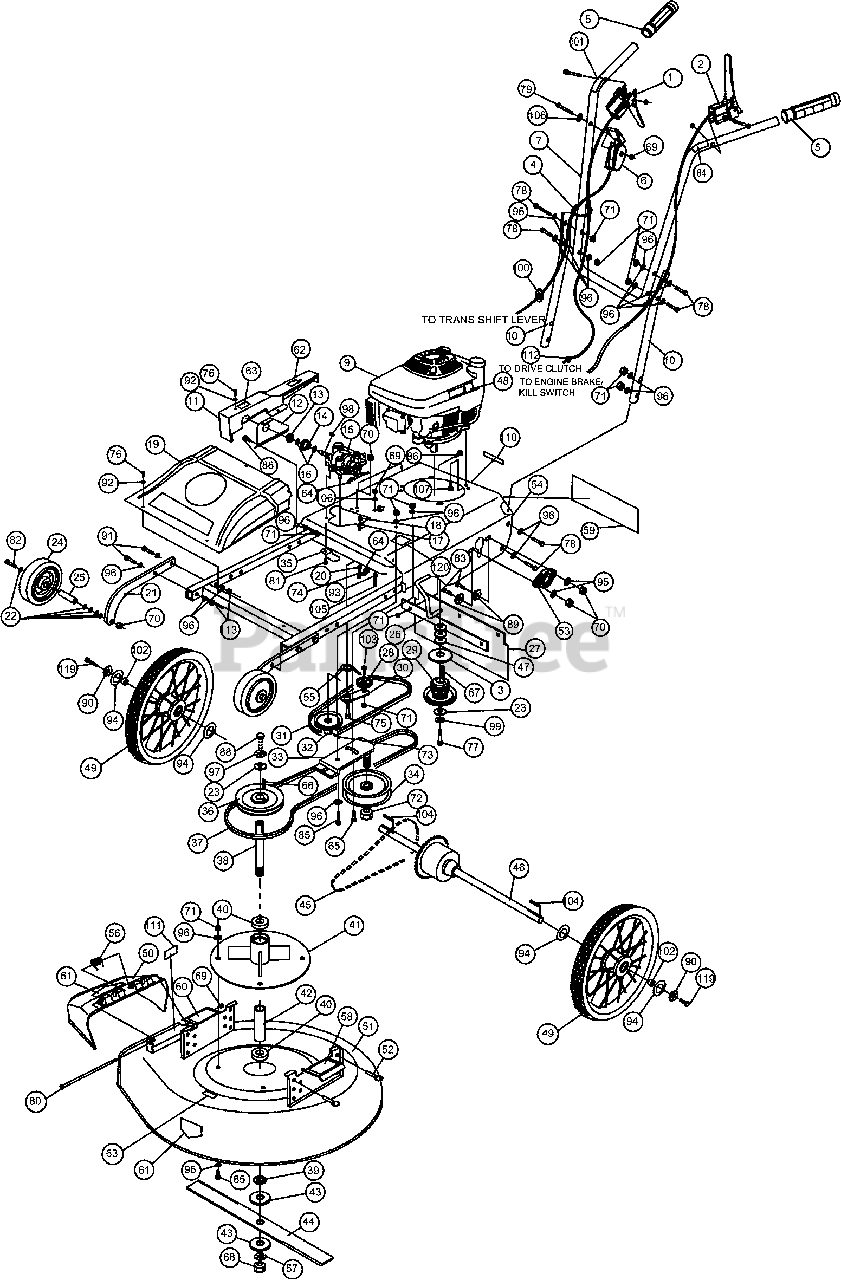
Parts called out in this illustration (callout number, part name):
1	LEVER DRIVE CLUTCH W/CABLE
2	LEVER ENGINE BRAKE W/CABLE
3	SPACER 1" ID X 2" OD
5	GRIP HANDLE 1” ID X 5” BLACK
6	CONTROL SHIFT 3 SPEED
7	HANDLE UPPER HW
9	ENGINE 6.5 HONDA OHV
10	HANDLE LOWER HW
11	CHAIN GUARD HW
12	PLATE BEARING RIGHT
13	BEARING 1/2 CLIP
14	8 TOOTH SPROCKET
15	TRANSMISSION 3 SP
16	C-CLIP 1/2
17	WASHER #10 SAE
18	LOCK NUT #10
19	BELT GUARD HW
20	NUT #10 HEX
21	FRONT WHEEL BRACKET
22	WASHER 1/2” ZP
23	WASHER 1/2" - .453 ID
24	WHEEL FRONT 6"’
25	SPACER WHEEL FRONT
26	PLATE DEFLECTOR MOUNT
27	RUBBER DEFLECTOR
28	PULLEY IDLER
29	PULLEY DOUBLE 2”/4” W/INERTIA-25MM
30	ARM IDLER TRANS WA HW
31	BELT 3L320
32	PULLEY 3” OD 10MM BORE
33	PLATE ENGINE IDLER WA HW
34	PULLEY IDLER
35	BRACKET TRANS LEVER
36	PULLEY 5.5” OD X 7/8” BORE
37	BELT BLADE 5L560
38	SHAFT DRIVE BLADE
39	SPACER SPINDLE BC2401
40	BEARING 7/8” SEALED
41	SPINDLE BLADE WA HW
42	TUBE SPACER SPINDLE
43	WASHER SPINDLE 2.5 OD
44	BLADE 23 1/2 W 7/8 HOLE
45	CHAIN #41 75 PITCH
46	REAR AXLE ASSY
47	SPACER HW HONDA
48	LABEL WARNING FUEL EN/SP
49	WHEEL SPOKE 16”
50	GUARD EXHAUST CHUTE
51	DECK ASSY W/LABELS
52	PIN 3/8X 1 1/2
53	BEARING 3/4 CAST FLANGE
54	BASE ASY W/LABELS
55	SPRING TRANS IDLER
56	SPRING EXHAUST CHUTE
57	WASHER LOCK 7/8 INT TOOTH
58	LABEL CUTTING HEIGHT
59	LABEL INSTRUCTION
60	LABEL WARNING MOWER
61	LABEL OPEI
62	LABEL OIL CHAIN
63	LABEL DANGER GUARDS
64	SPRING TENSION
65	CARRIAGE BOLT 5/16”-18X1
66	KEY SQ 3/16 X 5/8”
67	KEY SQ 1/4" X 1"
68	NUT JAM 7/8” -14
69	NUT LOCK 1/4-20 HEX ZP
70	NUT LOCK 3/8-16
71	NUT LOCK 5/16
72	NUT LOCK 5/8-11
73	ROLL PIN 3/16 X 1.25
74	SCREW MACHINE #10-24X 3/4
75	BOLT SHOULDER 1/2” X 1”
76	SCREW SELF TAP 1/4 X 3/4”
77	SCREW CAP 3/8-24 X 1 1/4”
78	SCREW CAP 5/16”-18X1 3/4
79	SCREW CAP 1/4-20 X 2 1/4”
80	SCREW CAP 1/4-20 X 7” ZP
81	SCREW SELF TAP 6 X 16
82	SCREWCAP 3/8-16 X 3”
83	SCREWCAP 3/8-16 X 1 1/2”
84	LABEL CLUTCH BLADE
85	SCREWCAP 5/16-18 X 1”
86	CARRIAGE BOLT 5/16-18X3/4
88	SCREWCAP 7/16-20 X 1 1/4 GR8
89	TWISTED WASHER 3/8”
90	TWISTED WASHER 5/16”
91	SCREW CAP 3/8-16 X2
92	WASHER 1/4 SAE BLACK
93	NUT JAM 1/4 - 20
94	WASHER 3/4 SAE
95	WASHER 3/8 FC
96	WASHER 5/16 FC
97	WASHER LOCK 7/16" S/T MED
98	KEY WOODWRUFF 1/8 X 1/2
99	WASHER LOCK 3/8 S/T MED
100	RUBBER GROMMET
101	LABEL CLUTCH DRIVE
102	SPACER NYLON BUSHING
103	SCREWCAP 5/16-18 X 1 1/2
104	KEY SQ. 3/16 X 2 1/8”
105	SCREW CAP 1/4-20 X 1 1/4
106	WASHER 1/4 SAE
107	SCREW 3/8 X 1 TAPTITE
110	LABEL SAFETY PROTECT READ MANUAL
111	LABEL FLYING DEBRIS
112	GROMMET 1” HOLE
113	NUT LOCK 3/8-16 THIN
119	SCREWCAP 5/16" - 18 X 3/4" HCS ZP
120	LABEL MADE IN U.S.A.
